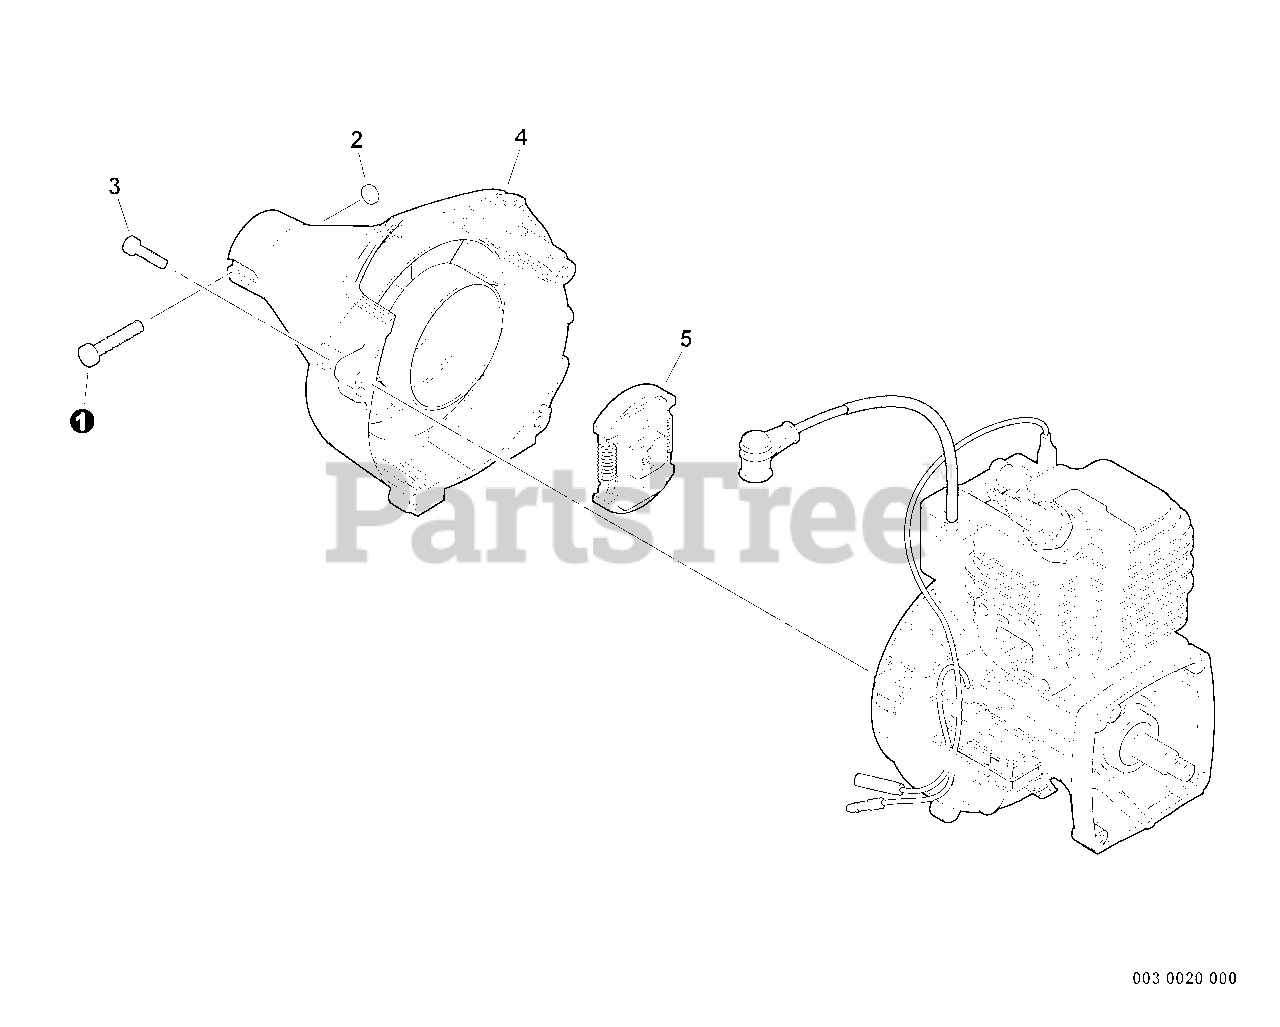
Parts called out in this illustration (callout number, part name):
1	BOLT, TORX 5×25
2	NUT M5
3	BOLT, TORX 4×16
4	FAN CASE ASSY
5	CLUTCH ASSY
